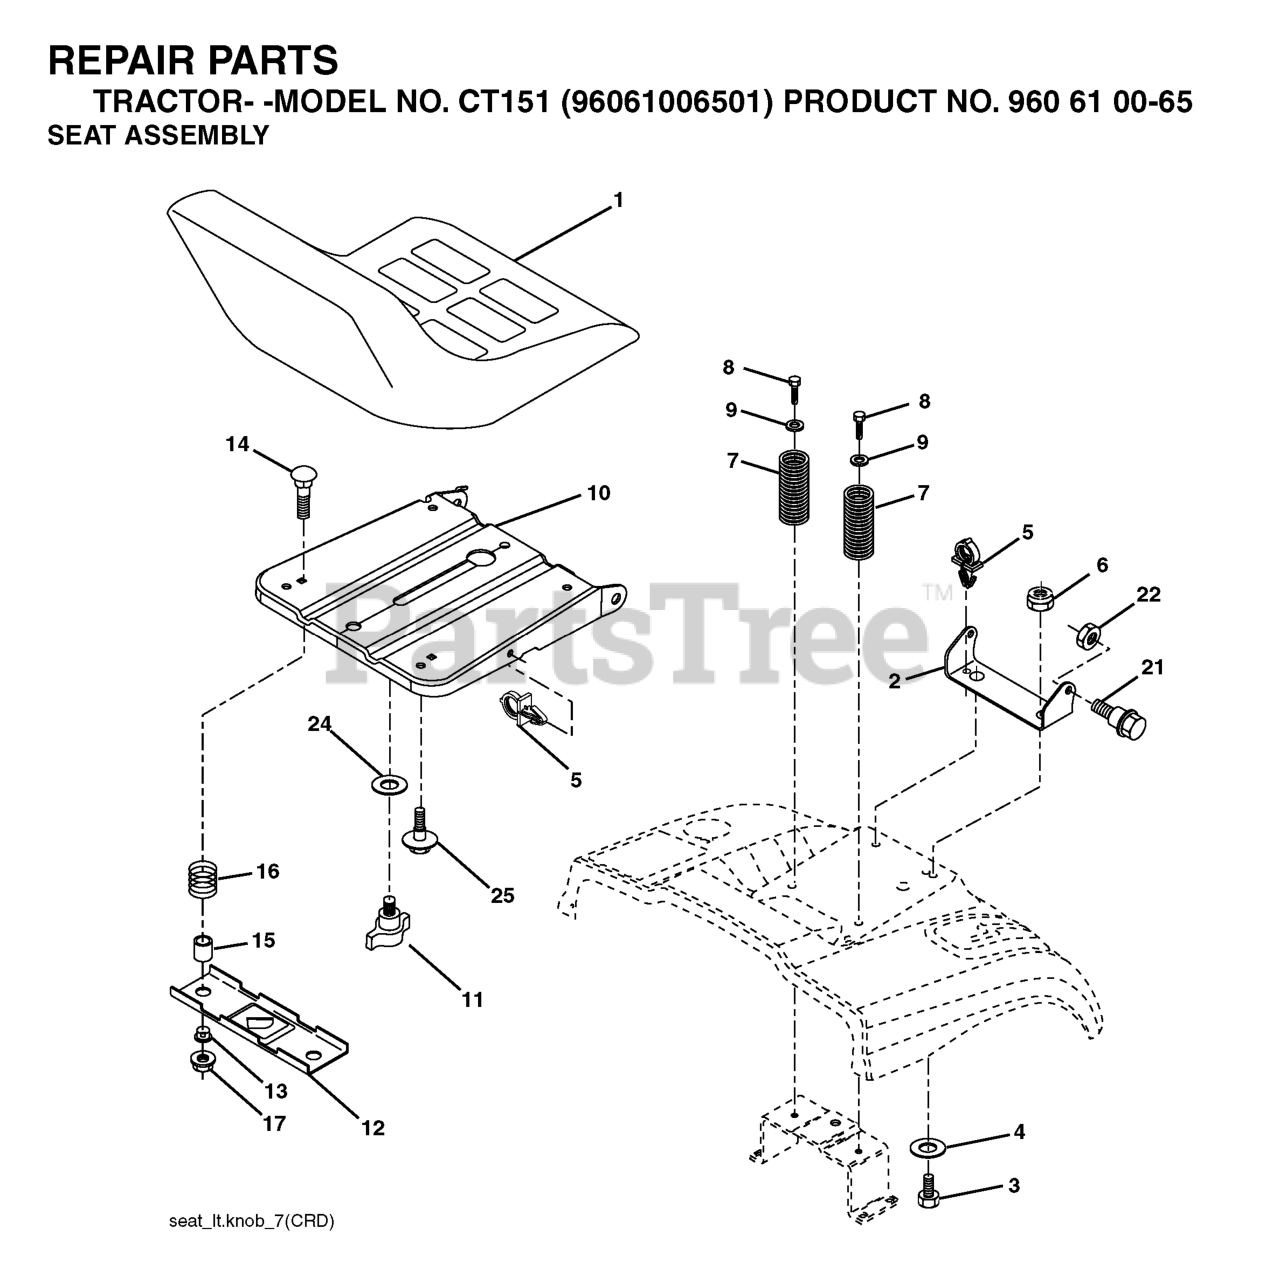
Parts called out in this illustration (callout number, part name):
1	RP SEAT
2	SEAT PIVOT BRKT
3	BOLT, HEX 3/8-16X1
6	NUT
7	SPRING COMPRESSION
8	SCREW 3/8-16X1
9	WASHER
10	PAN.ASM.SEAT.1SLOT
11	KNOB.SEAT.ADJ.WINGNUT
12	BRKT.MNTNG.SWITCH.SEAT.BLACK
14	BOLT.ROUND.HEAD.SQUARE.NECK
15	SPACER SPLIT 28X.96
17	NUT T
21	BOLT.SHOULDER.5/16-18
22	NUT.71038.31-18.HEX.NYLOCK
25	BOLT,SHOULD
